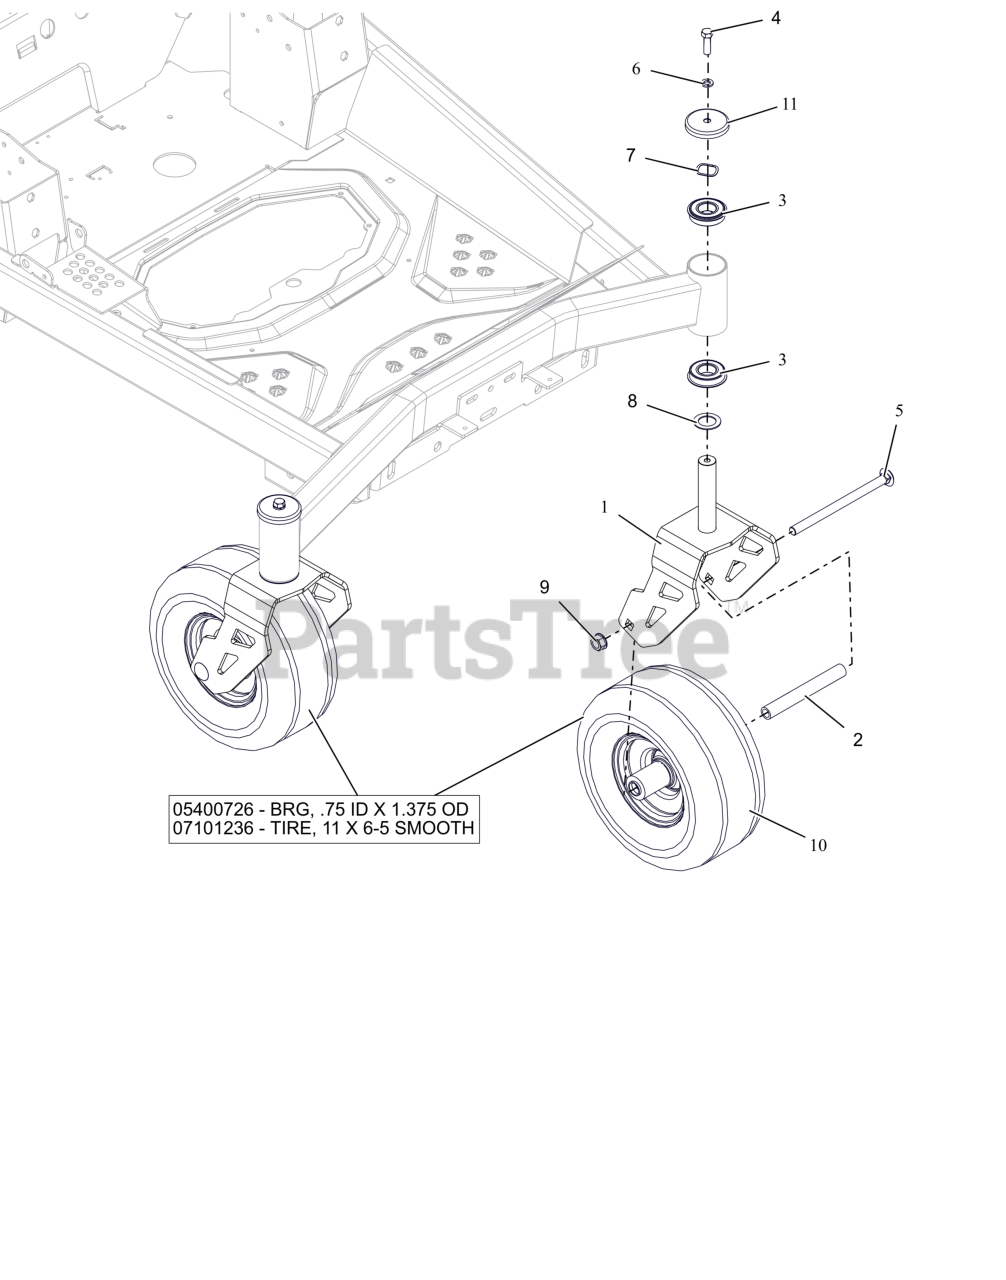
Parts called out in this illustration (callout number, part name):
1	WLDMT, CASTER FORK (ORANGE)
2	SPACER, FRONT WHEEL (WIDE 6.0)
3	BEARING, BALL -2.000 OD X 1.000 ID X .5625 W/RING
4	BLT- HEX .38-16X1.25 G5 ZB500
5	BLT, RHSN .50-13X7.50 G5 ZCC
6	WSHR-LK-REG .375X.094 ZB500
7	WSHR-WAVE 1.0X1.25X.028 .145FH
8	WSHR-HRD-THRS 1.007X1.542X.062
9	NUT-LK-CTR-FLG .500-13 GG ZCC
10	TIRE/WHEEL ASSY 11X6-5
10	BRG, .75 ID X 1.375 OD
10	LAWN TIRE FRONT, 11/6.00-5 SMOOTH
11	SHIELD, AXLE BEARING
